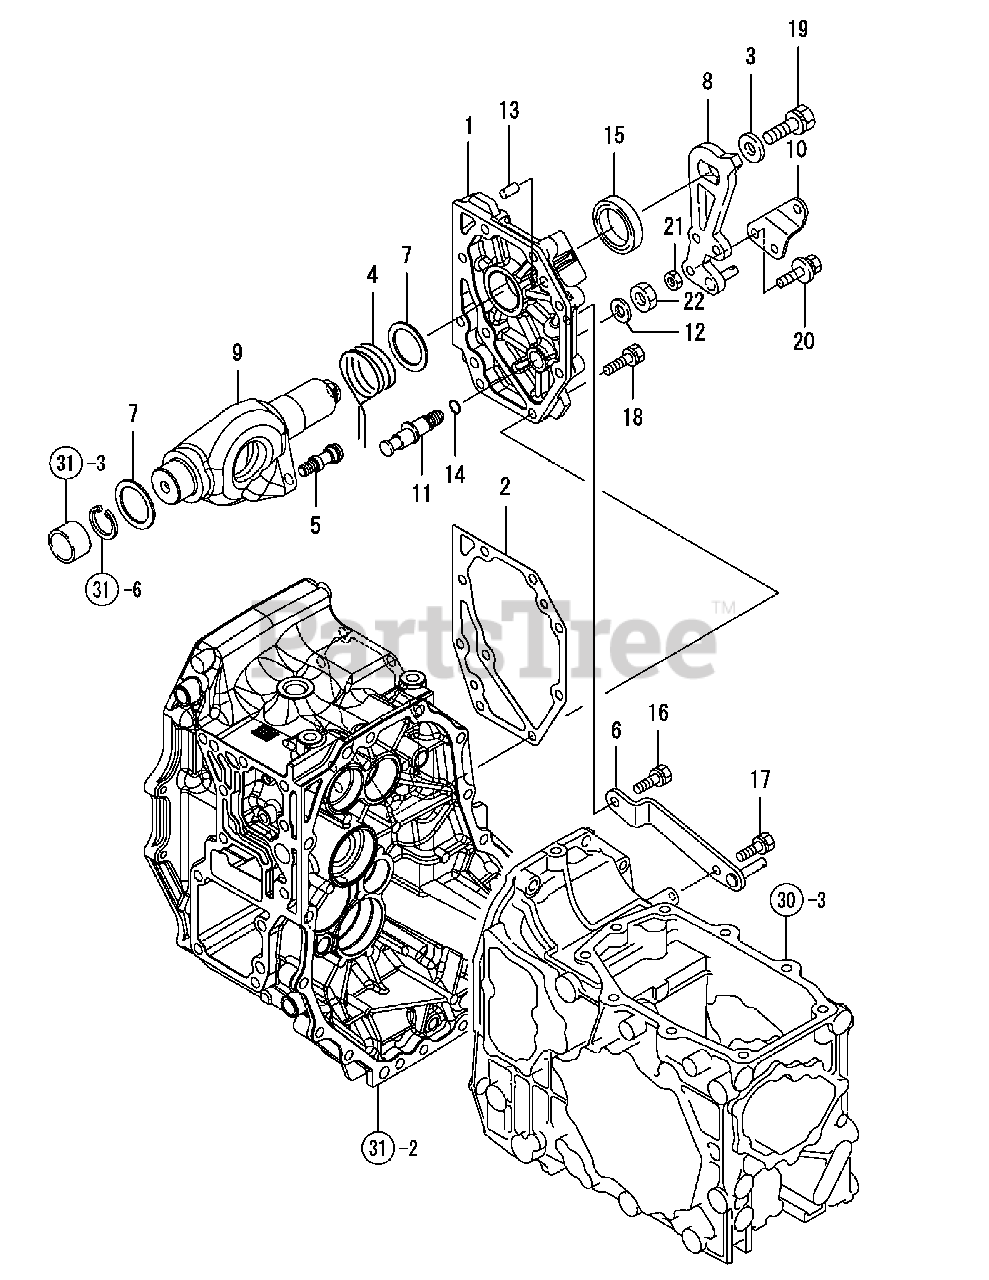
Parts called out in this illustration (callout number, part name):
1	Cover Assy, Side R
2	Gasket, Side Cover R
3	Washer 12X27X4.5
4	Spring, Return
5	Fulcrum, N Center
6	Stay Cmp, Absorber
7	Washer, 35X47X2
8	Control Arm Comp.
10	Plate, Control Arm
12	Washer 12,Polished
13	Parallel Pin 8X 16
14	O-Ring 1A P-10A
15	Seal Tc35 50 08, Oil
22	Lock Nut M12 Plated
